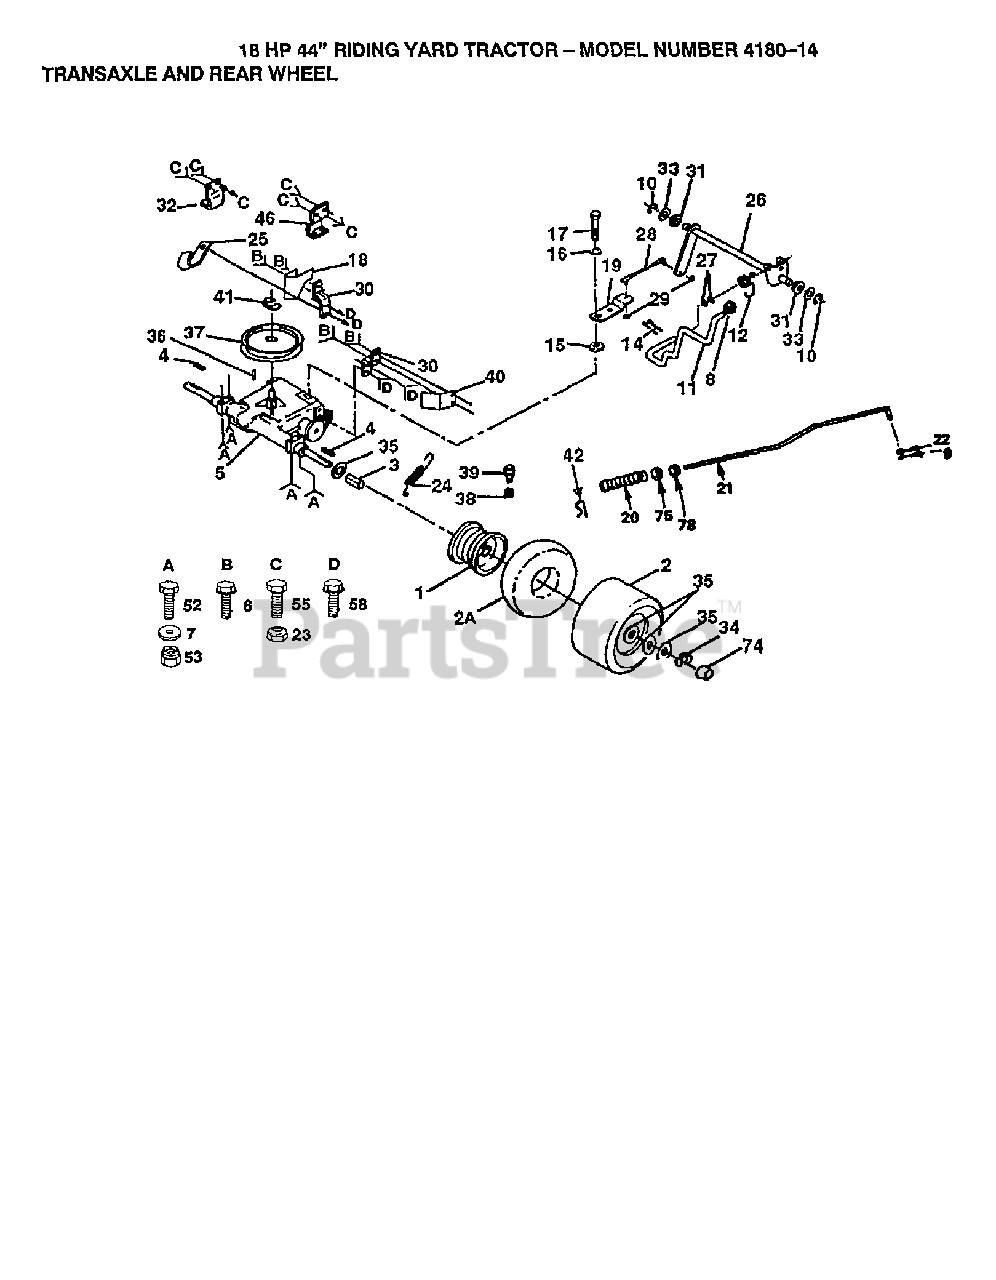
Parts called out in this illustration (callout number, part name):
2	Tire, .23 X 8.5-12 Turf Saver
2A	TUBE.23"X9.5""X12""
3	SPACER HYT
5	TRANSAXLE NLA
8	KNOB T (1/2-HOLE)
9	COTTER PIN
10	KLIP RING
11	ROD SHIFTER
12	SPRING,TORSION
14	PIN COTTER
15	WASH-SHFT PLT LT
16	WASHER PM
18	KEEPER BELT LH
19	ARM,SHIFT
20	SPRING,ROD BRAKE
21	ROD BRAKE
23	LOCKNUT
24	SPRING T
25	CLIP T
26	SHAFT,SHIFTER
27	WASHER
29	NUT 1/4-28
30	STRAP TORQUE
31	BUSHING.STEERING.ROD
32	BRKT TRANS LH
33	WASHER D
34	E RING HYT
36	KEY.WOODRUFF
37	PULLEY TRANSAXLE
38	VALVE CAP
39	VALVE STEM LT
40	KEEPER,BELT RH
42	RETAINER M
46	BRKT TRANS RH
52	BOLT HEX
53	LOCKNUT
58	Screw, Lt
74	CAP.HUB.FRONT.LT.BLACK
75	NUT
78	NUT
